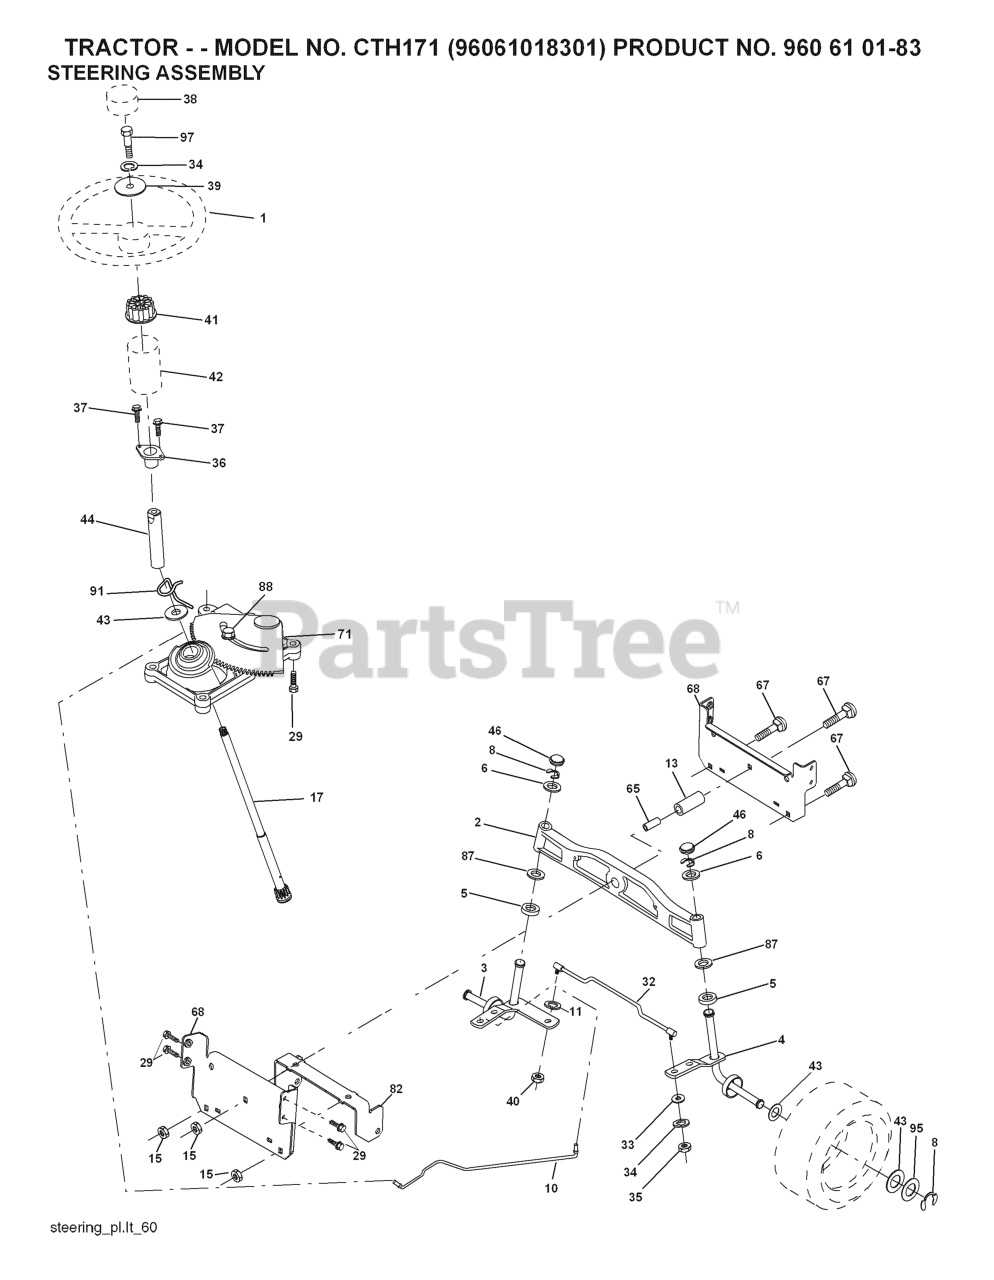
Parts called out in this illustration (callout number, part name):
1	STEERING WHEEL
2	AXLE ASSY FRONT
3	SPINDLE.ASM.LH.15"TIRES
4	SPINDLE.ASM.RH.15"TIRES
5	THRUST WASHER
10	DRAGLINK.15".TIRES.2001
11	WASHER, LOCK 3/8
13	TUBE, PIVOT AXLE
15	NUT
17	SHAFT STEERING SPLINE
29	SCREW, 3/8-16X3/4
32	TIE ROD
33	WASHER M
34	WASHER.LOCK.HVY.HLCL.SPR.5/16
35	NUT, CROWNLOCK
36	BUSHING, STEERING
37	SCREW.TT.#10-32X.5.3/8.FLANGE
38	INSERT.CAP.STRG.WH.GRAY
39	WASHER.11/32
40	NUT CROWNLOCK 3/8-24
41	ADAPTER, WHEEL STNG..
42	BOOT, STEERING
44	SHAFT.EXTEN.STRG.SPLINE
46	CAP.SPINDLE.BLACK
65	SPACER BRACE AXLE
67	BOLT CARRIAGE
68	BRACE.AXLE.15"TIRES
71	STEERING ASM
82	BRACKET.SUSP.CHASSIS.FRONT.15
87	WASHER, FLAT .781 X 1 1/2"
88	BOLT, SHOULDER 7/16-20
91	CLIP.STEERING
95	WASHER.HARDENED
